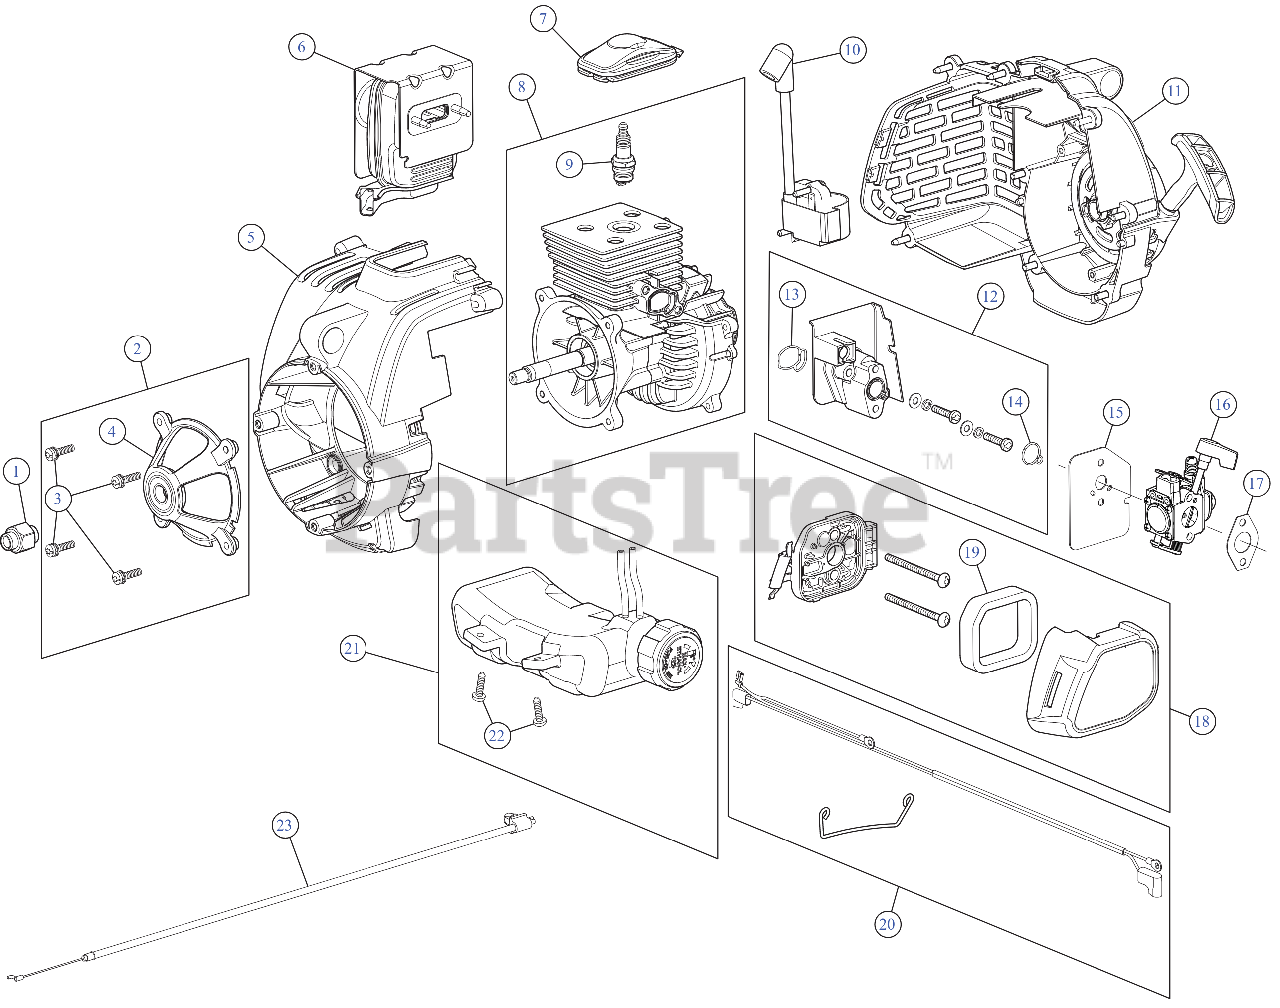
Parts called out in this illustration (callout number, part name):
1	FLYWHEEL ADPT
2	BEARING HLDR ASSEMBLY
3	SCREW M5X0.8-20
4	BEARING HOLDER
5	COVER ASSEMBLY (FRONT)
6	MUFFLER ASSEMBLY
7	SPARK PLUG COVER
8	SHORT BLOCK
9	SPARK PLUG
10	MODULE BLOWER
11	COVER ASSEMBLY (REAR)
12	INTAKE ASSEMBLY BLOWER
13	O-RING
14	O-RING
15	CARBURETOR GASKET
16	CARBURETOR
17	GASKET CARB
18	AIRCLEANER COVER ASSEMBLY
19	AIR FLITER
20	WIRE LEAD BLOWER
21	FUEL TANK ASSEMBLY
22	SCREW:10-6 x .75
23	THROTTLE CABLE
